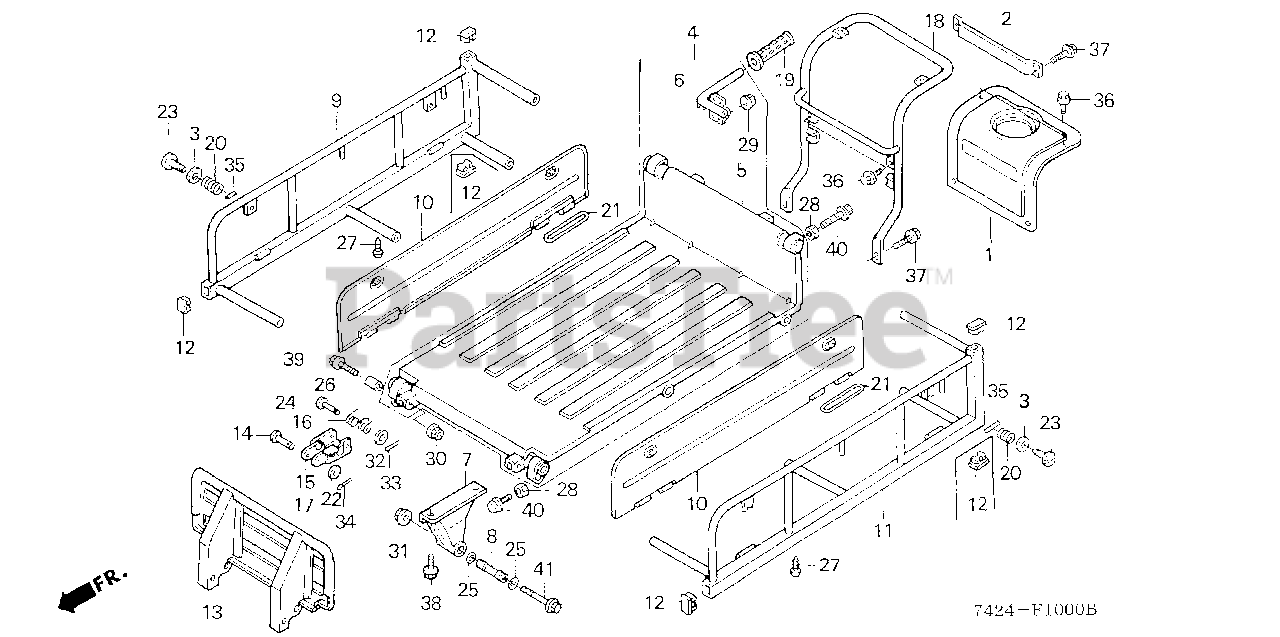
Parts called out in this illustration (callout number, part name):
1	PLATE, TANK GUARD *NH35M* (CLOUD SILVER METALLIC)
2	PLATE, CLUTCH ARM GUARD
3	RETAINER, LOCK SPRING
4	BODY ASSY., CARRIER *NH35M* (CLOUD SILVER METALLIC)
5	BODY, CARRIER *NH35M* (CLOUD SILVER METALLIC)
6	HANDLE, CARRIER *NH35M* (CLOUD SILVER METALLIC)
7	BRACKET, CARRIER
8	COLLAR, CARRIER BRACKET
9	PIPE, R. GUIDE
10	PLATE, CARRIER SIDE PANEL *NH35M* (CLOUD SILVER METALLIC)
11	PIPE, L. GUIDE
12	CAP, PIPE GUIDE
13	PLATE, FR. STOPPER *NH35M* (CLOUD SILVER METALLIC)
14	PIN A, FR. STOPPER LOCK
15	LOCK ASSY., R. FR. STOPPER
16	SPRING, FR. STOPPER
17	LOCK ASSY., L. FR. STOPPER
18	PIPE, ENGINE GUARD
19	GRIP, R. HANDLE
20	SPRING, COVER LOCK
21	PIN, CHUTE GUIDE
22	WASHER, FR. STOPPER LOCK
23	PIN, COVER LOCK
24	PIN, FR. STOPPER
25	O-RING (16MM)
26	COLLAR, FR. STOPPER
27	SCREW, TAPPING (5X16)
28	NUT, HEX. (10MM)
29	NUT, FLANGE (8MM)
30	NUT, FLANGE (10MM)
31	NUT, FLANGE (12MM)
32	WASHER, PLAIN (10MM)
33	PIN, COTTER (2.0X22)
33	PIN, COTTER (2.0X35)
34	PIN, COTTER (2.5MM)
35	PIN, SPRING (3X18)
36	BOLT, FLANGE (6X10)
37	BOLT, FLANGE (8X16)
38	BOLT, FLANGE (10X20)
39	BOLT, FLANGE (10X45)
40	BOLT, FLANGE (10X32)
41	BOLT, FLANGE (12X70)
